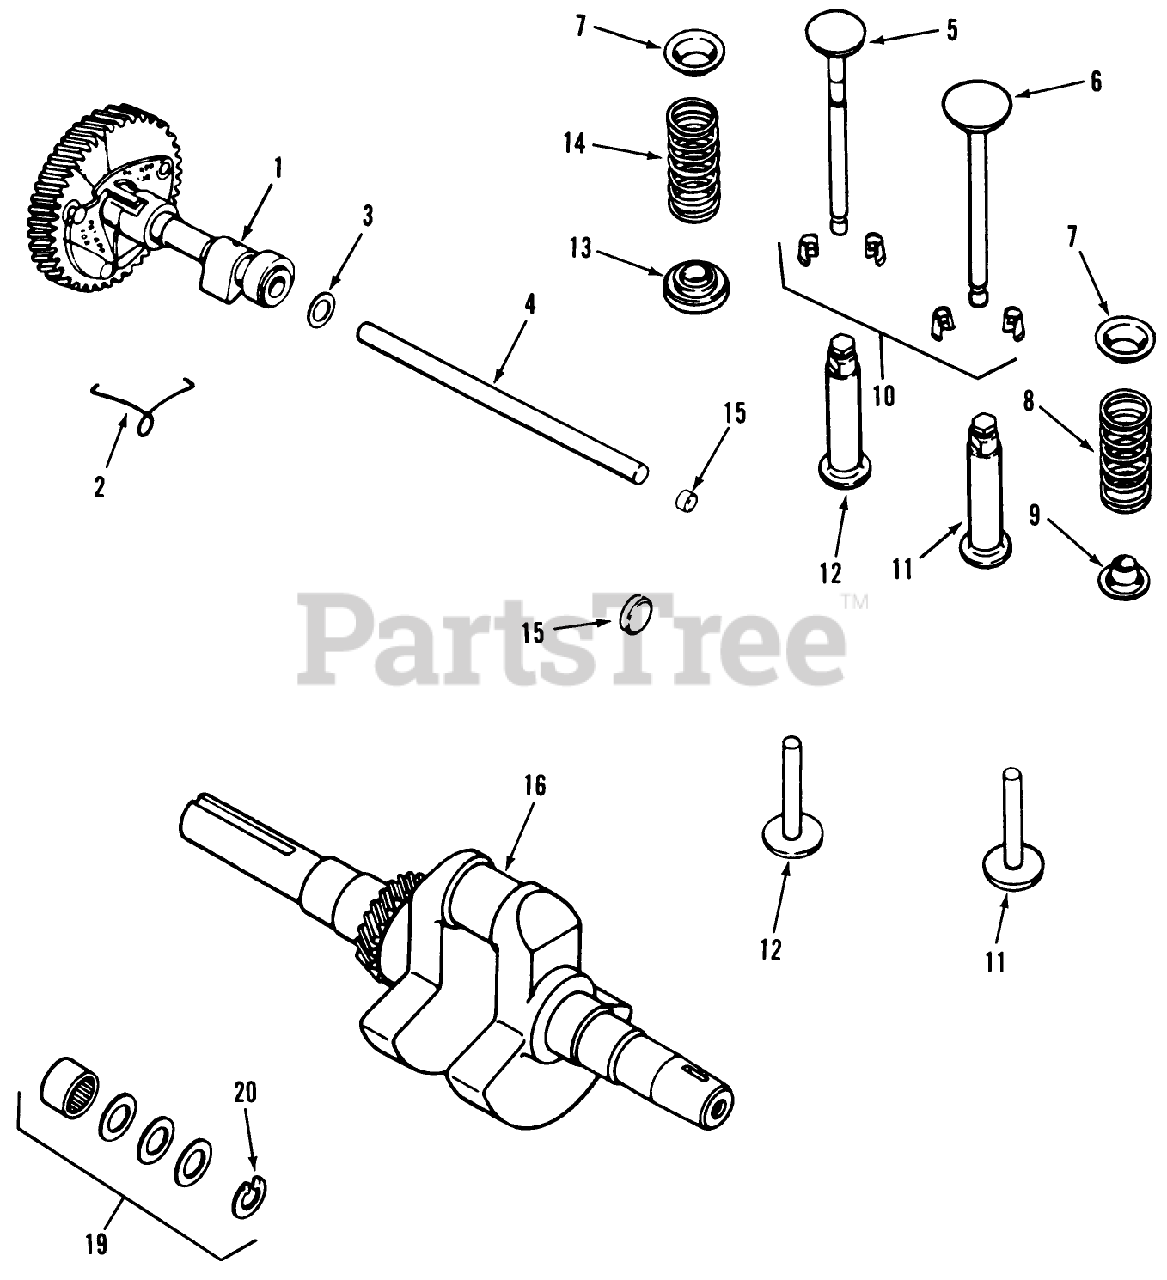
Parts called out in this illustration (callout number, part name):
1	VNDR# 25-757-13
2	KOHLER 47-089-01
3	KOHLER 275066
4	KOHLER 47-380-09
5	KOHLER 235838
6	KOHLER 235008
7	KOHLER 235011
8	KOHLER 235010
9	KOHLER 230011
10	KOHLER 41-755-10
11	KOHLER D-235327
12	KOHLER D-235327
13	KOHLER 52-413-01
14	KOHLER 235010
15	KOHLER X-702-3
16	KOHLER 47-142-02
19	KOHLER 47-755-01
20	KOHLER X-269-34
